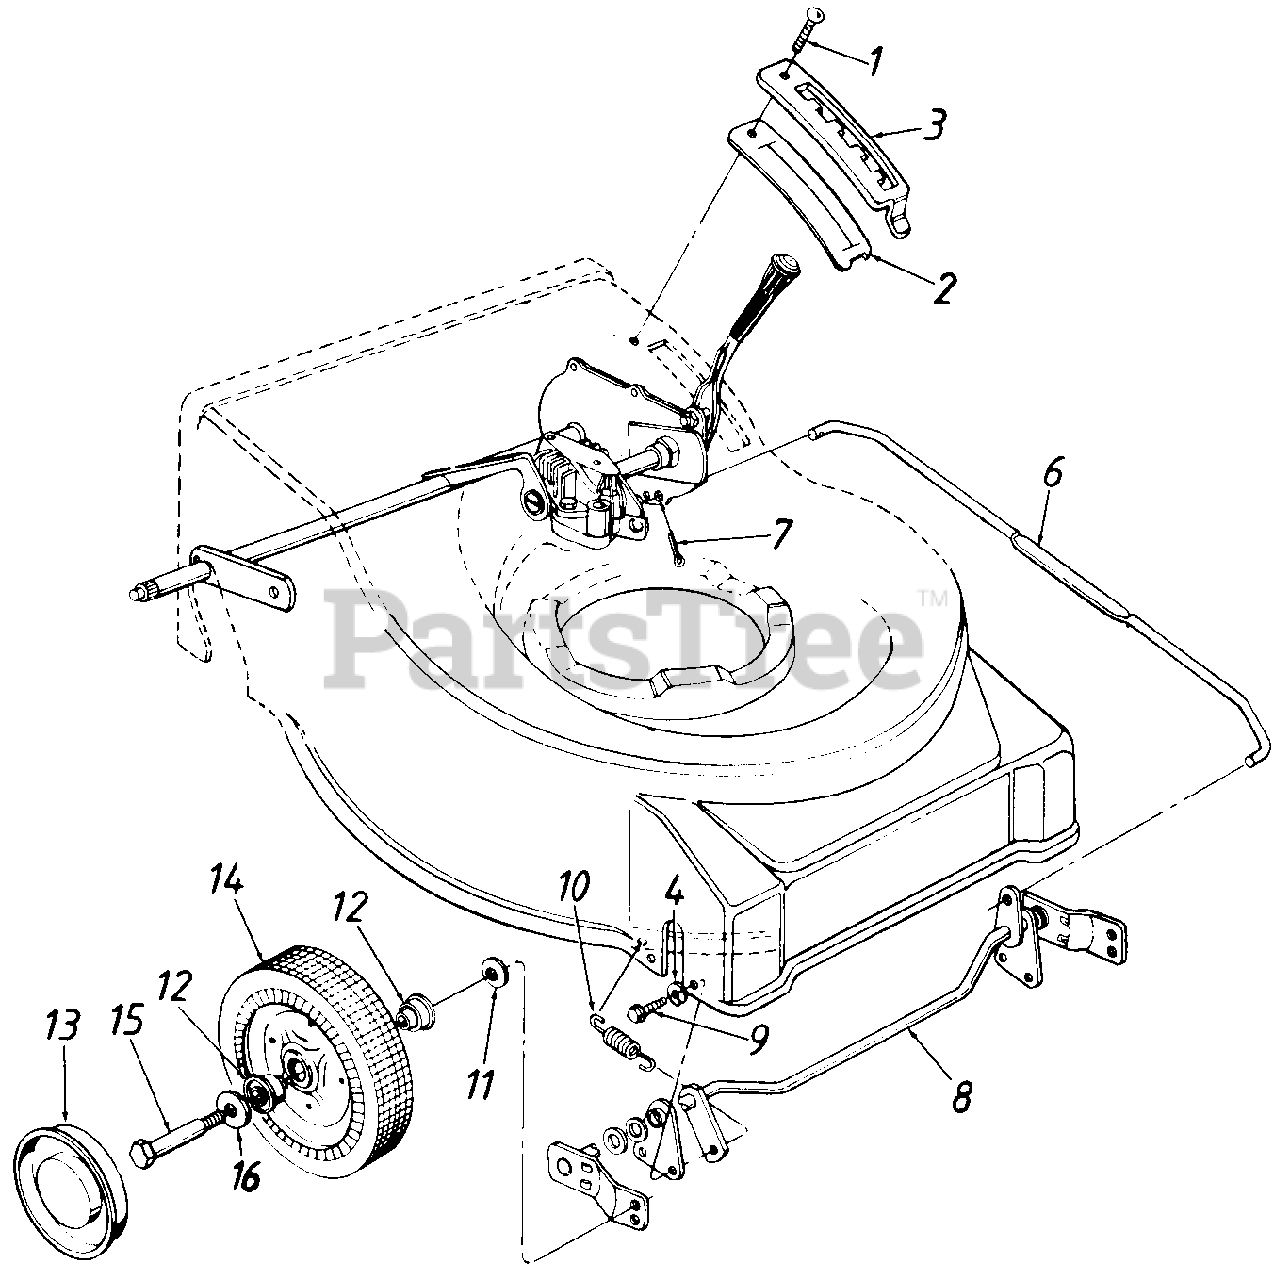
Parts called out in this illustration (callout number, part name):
1	Torx Mach. AB-Tap Scr. 1/4 X .62" Lg.
2	Height Adjustment Support
3	Height Adjustment Plate
4	L-Wash. 1/4" I.D.
6	Height Adj. Connecting Rod
7	Cotter Pin 3/32" Dia.
8	Front Axle Ass'y.
9	Hex L-Wash. Hd. AB-Tap Scr. 1/4 x.38" Lg.
10	Extension Spring 2.39" Lg.
11	Bell-Wash. 380" l.D. x .88" O.D.
12	Flange Ball Bearing 1/2" I.D.
13	Hub Cap
14	Wheel Ass'y. Comp.-Front
15	Shld. Bolt .498" Dia. x 1.45"
16	Fl-Wash. .531" I.D. x .93" O.D.
